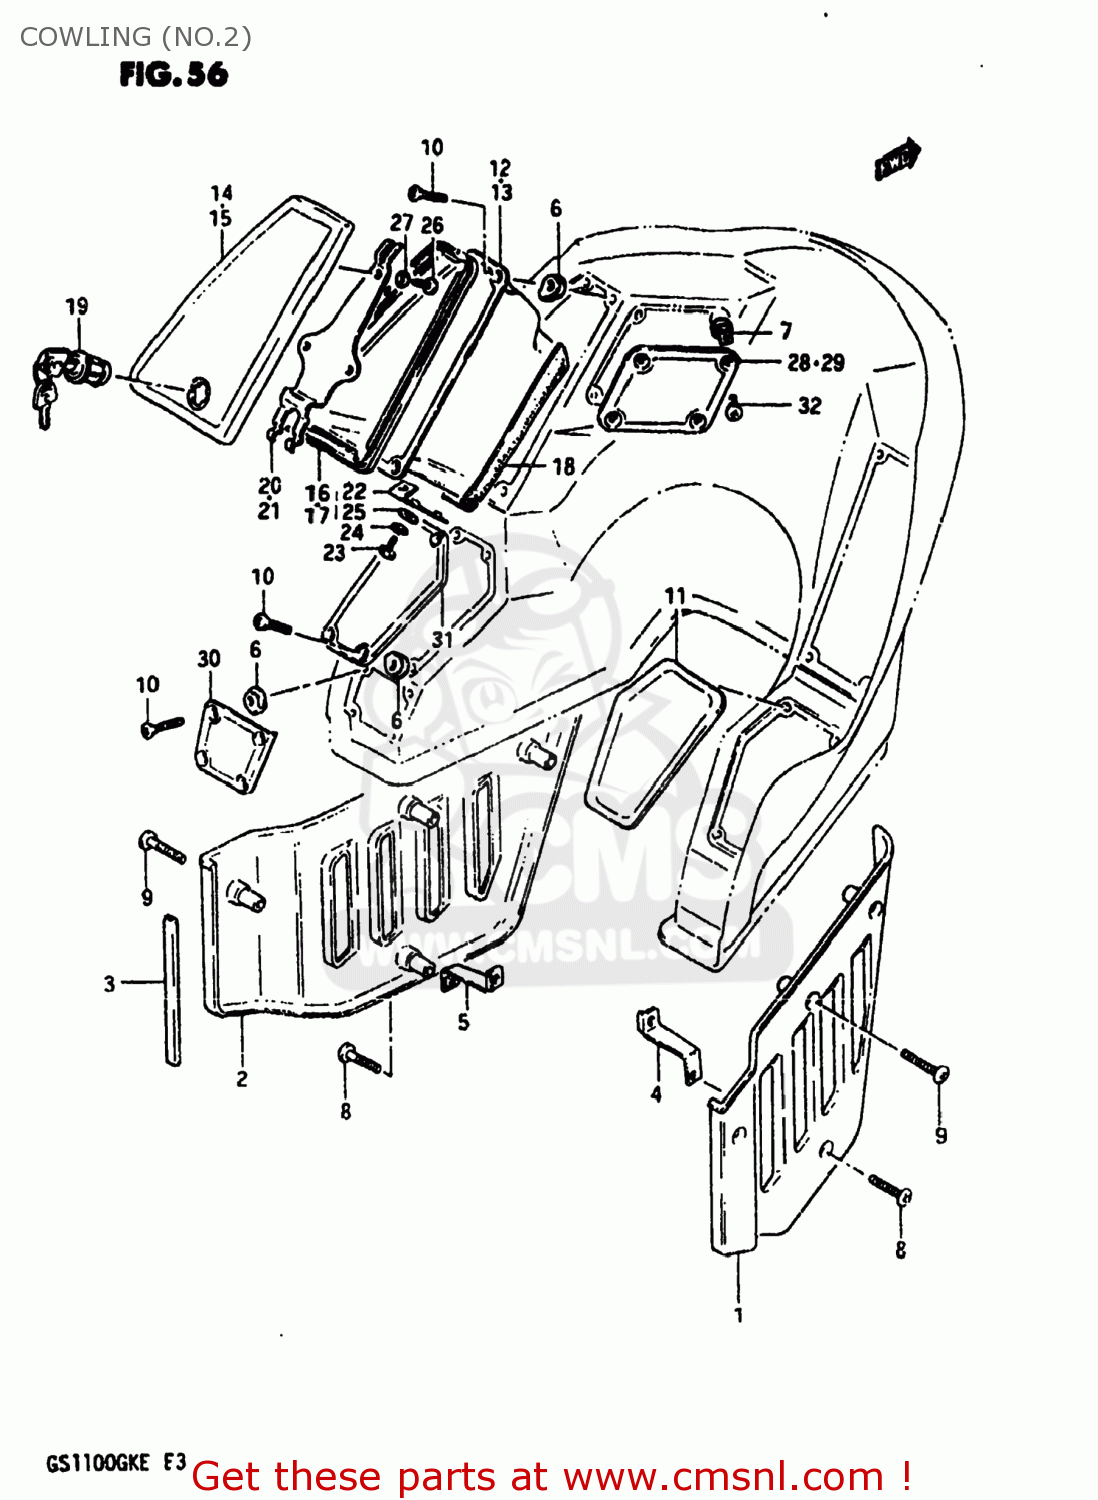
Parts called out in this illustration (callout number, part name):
1	COVER,COWLING,LOWER,RIGHT
2	COVER,COWLING,LEFT
3	MOLDING,COWLING LOWER COVER
4	BRACKET
5	BRACKET
6	PLATE,COVER FITTING NO
7	PLATE,COVER FITTING NO
8	SCREW
9	SCREW
10	SCREW (5X16)
11	GLOVE BOX,COWLING (BLACK)
12	CONSOLE BOX,RIGHT
13	CONSOLE BOX,LEFT
14	LID,CONSOLE BOX,RIGHT
15	LID,CONSOLE BOX,LEFT
16	CUSHION,CONSOLE BOX
17	CUSHION,CONSOLE BOX,LEFT
18	CUSHION CONSOLE BOX
19	LOCK,CONSOLE BOX
20	PLATE,LOCK HOLDER,RIGHT
21	PLATE,LOCK HOLDER,LEFT
22	PLATE,LOCK HOLDER SUPPORT
23	BOLT
24	LOCK WASHER
25	WASHER
26	SCREW
27	WASHER
28	COVER,SPEAKER,RIGHT
29	COVER,SPEAKER,LEFT
30	COVER,CB CONTROLER
31	COVER,RADIO CASE,LEFT
32	SCREW (5X30)
